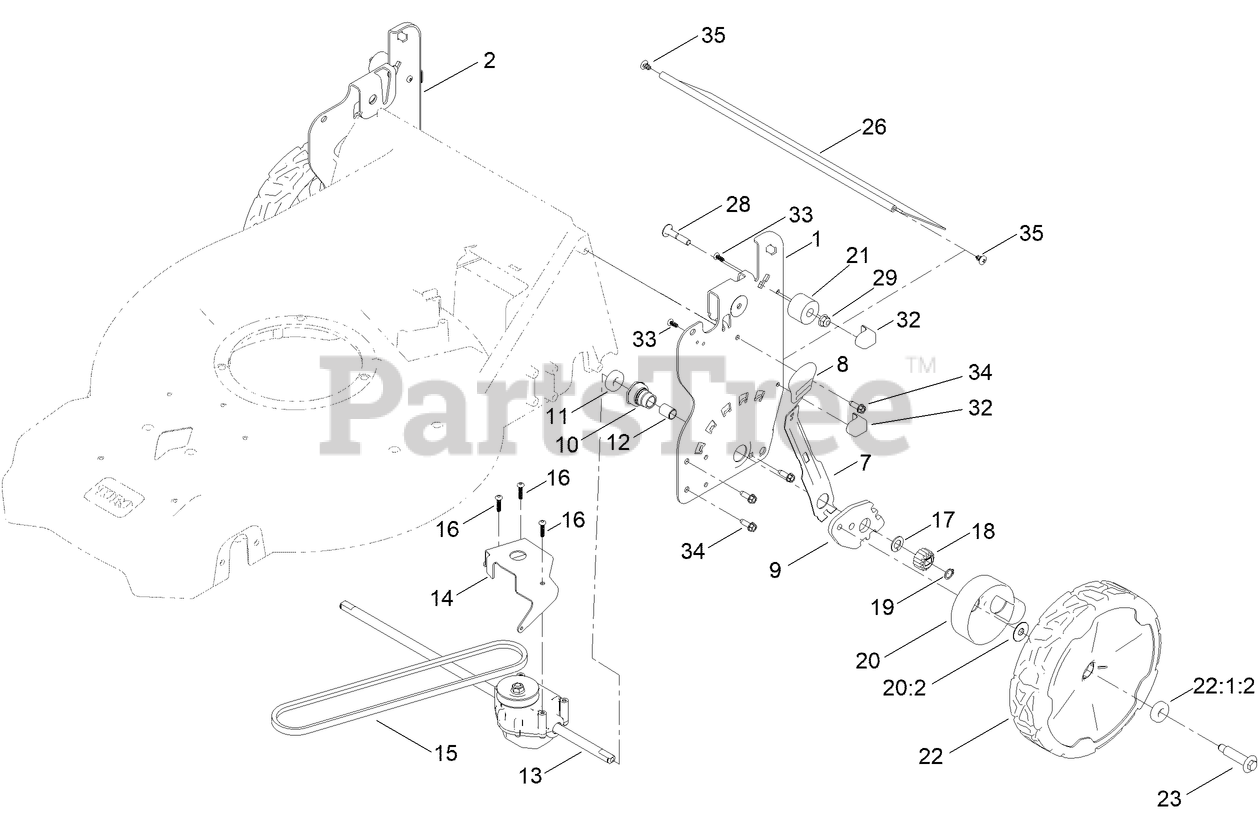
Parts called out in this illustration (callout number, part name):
1	PLATE-HOC, LH (ISO)
2	PLATE-HOC, RH (ISO)
7	ARM-SPRING
8	KNOB-HOC
9	ARM-PIVOT, REAR
10	RETAINER-BUSHING, HOC
11	BEARING-WHEEL
12	BUSHING-SLEEVE
13	TRANSMISSION-RWD, 5.25:1
14	BRACKET-TRANS, RWD HI
15	BELT-V
16	SCREW-PLASTITE
17	WASHER-THRUST
18	GEAR-PINION, 15T
19	RING-RETAINING
20	ASM-COVER, GEAR
20:2	WASHER-STEPPED
21	BUMPER-ISOLATOR
22	ASM-9.65" WHEEL, GEARED
22:1:2	BEARING-WHEEL
23	WHEEL BOLT
26	SHIELD-TRAILING
28	SCREW-CARR-SPCL
29	NUT-HF, NI
32	PAD-SMART STOW
33	SCREW-PLASTITE
34	SCREW-HWHTF
35	SCREW-PTH
